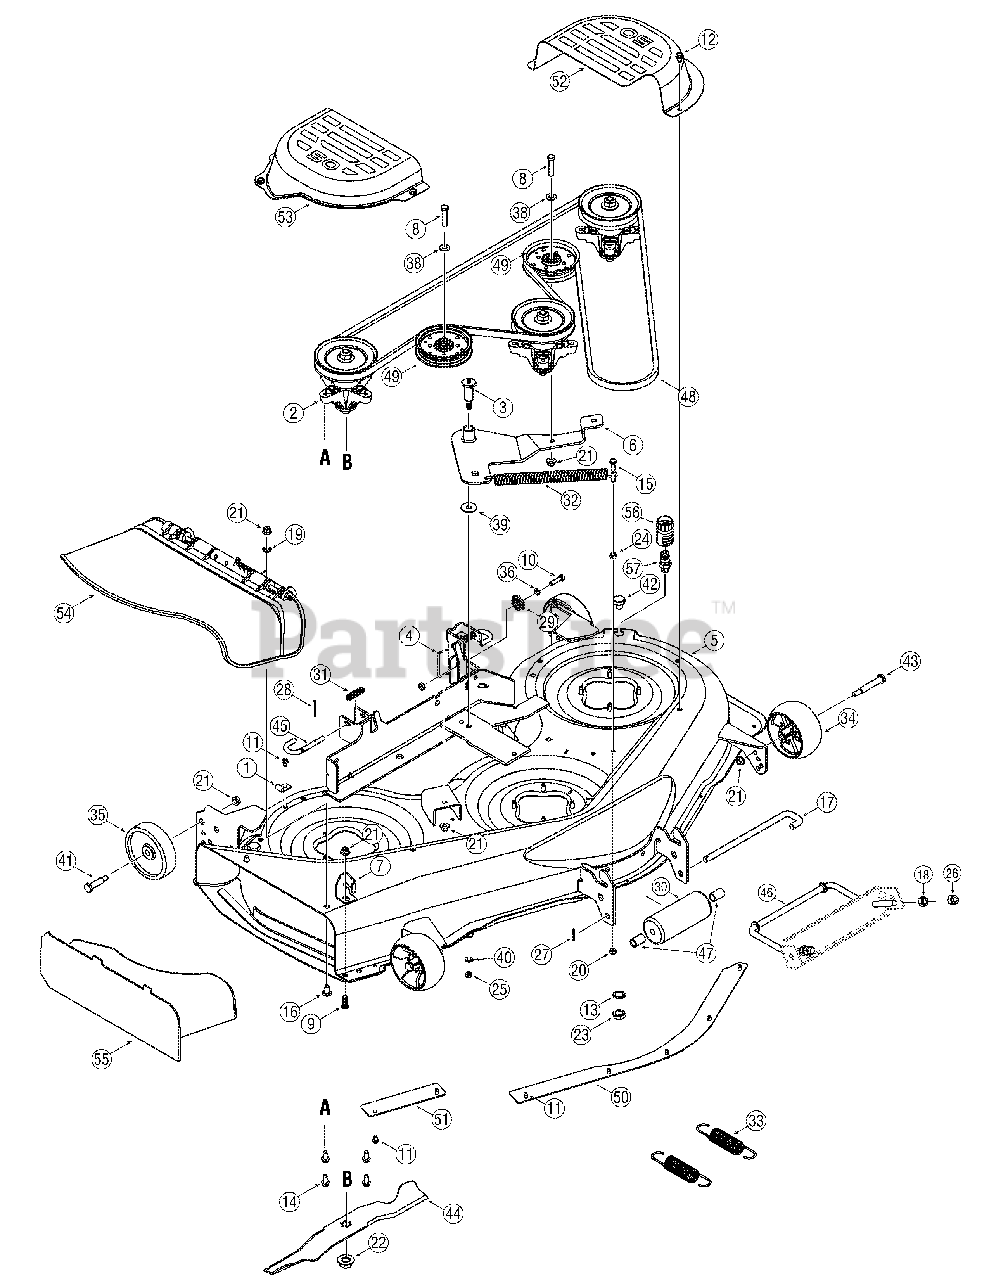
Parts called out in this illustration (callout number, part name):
1	Hook, Retainer
2	Spindle Assembly
3	Shoulder Bolt
8	Screw, 3/8-16, 1.75
9	Screw, 3/8-16 x 1.0
10	Screw, 5/16-18, 1.25, Gr5
11	Screw, 1/4-20 x 0.5
12	Screw, 5/16-18 x .75
13	Washer, Lock, 5/8 Internal Tooth
14	Screw, 5/16-18 x .75
15	Screw, 5/16-18 x 2.00
16	Screw, Carriage, 3/8-16 x .75
17	Roller Pin
18	Hex Nut, 1/2-13
19	Push Nut Retainer
20	Nut, Nylon Lock, 5/16-18
21	Nut, Nylon Lock, 3/8-16
22	Nut, Hex, Flange, 5/8-18
23	Nut, Hex, M16-1.5
24	Nut, Hex, 5/16-18, Gr5
25	Hex Nut, 7/16-14
26	Hex Lock Nut, 1/2-13
27	Pin, Cotter, 3/32 x 1.00
28	Pin, Cotter, 1/8 x 1.25
29	Deck Adjustment Gear
31	Spring, Compression, .531 x 1.75
32	Spring, Extension, .94 x 6.74
33	Spring, Extension, 1.5 x 5.99
34	Deck Wheel, 5.0
35	Deck Wheel, 5.0
36	Washer, Lock, 5/16
37	Washer, Lock, 5/8"
38	Washer, Flat, .406 x .875 x .059
39	Washer, Flat, .442 x 1.38 x .060
40	Washer, Bell, .45 x 1.00 x .062
41	Shoulder Screw
42	Bolt, Plug, M16 x 1.5
43	Shoulder Screw
44	Blade, 17.90
45	Rod, Deck Release .375 Dia.
46	Rod, Deck Adjust
47	Spacer, .550 x .750 x 1.125
48	Belt, V-Type, Aramid
49	Pulley, Idler, 3.5"
54	Chute Assembly, Side Discharge
55	Mulch Plug
56	Coupler, Hose
57	Port, Water
